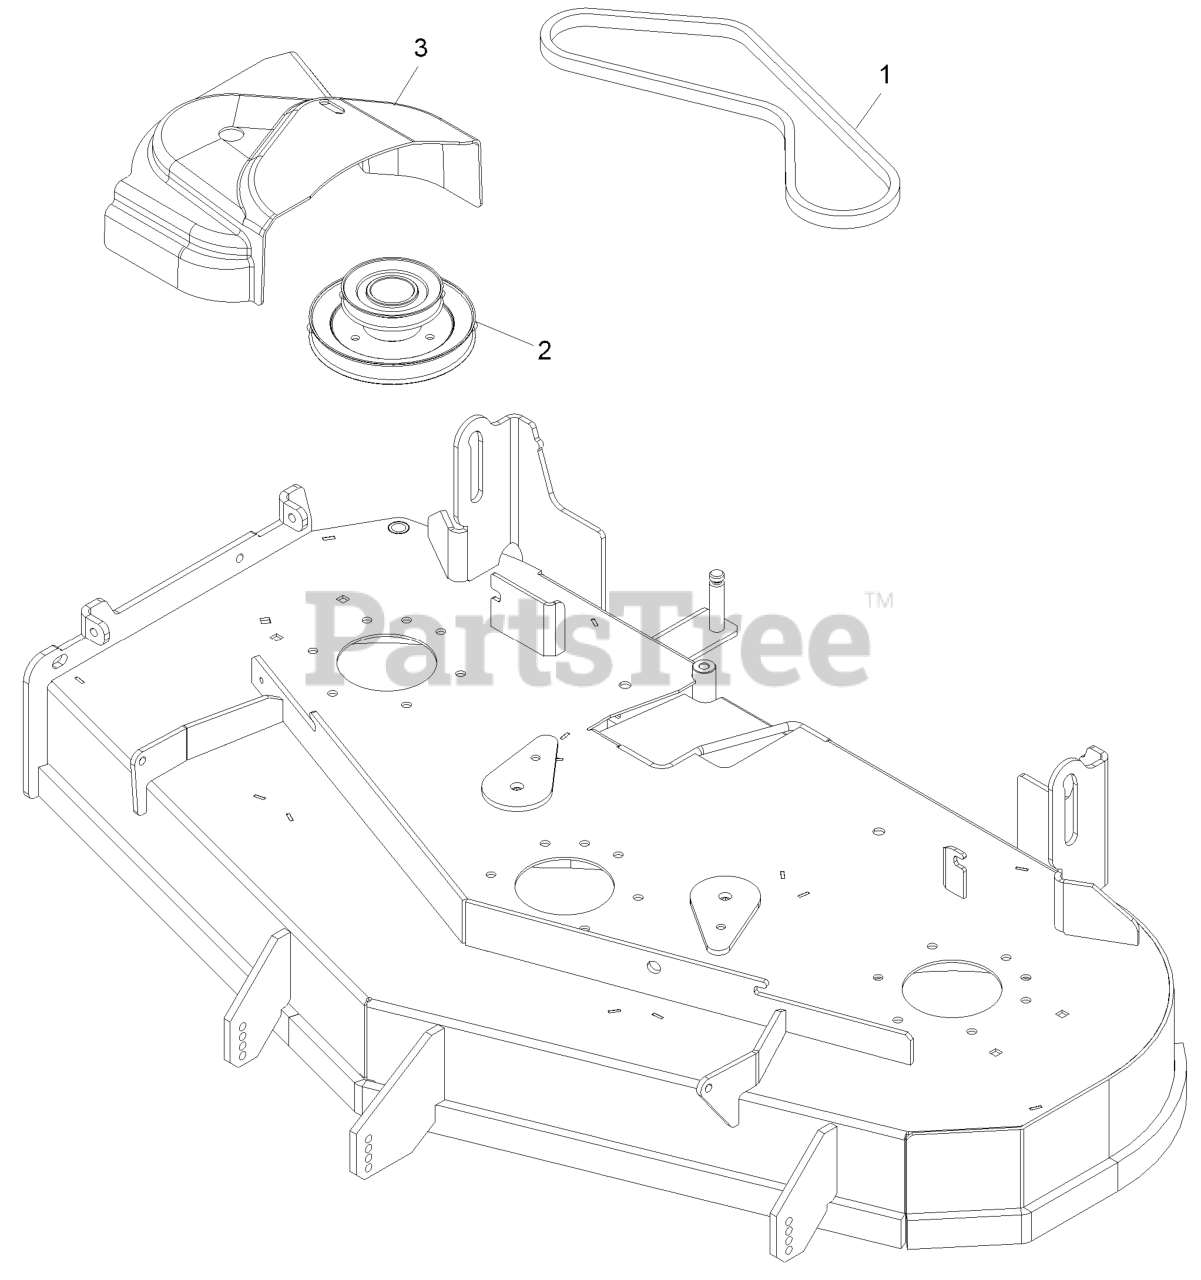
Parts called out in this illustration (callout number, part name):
1	Belt, Blower Drive 52
2	Jackshaft,Uv Drive 524 Splined
3	Cover,Belt Uv 52
